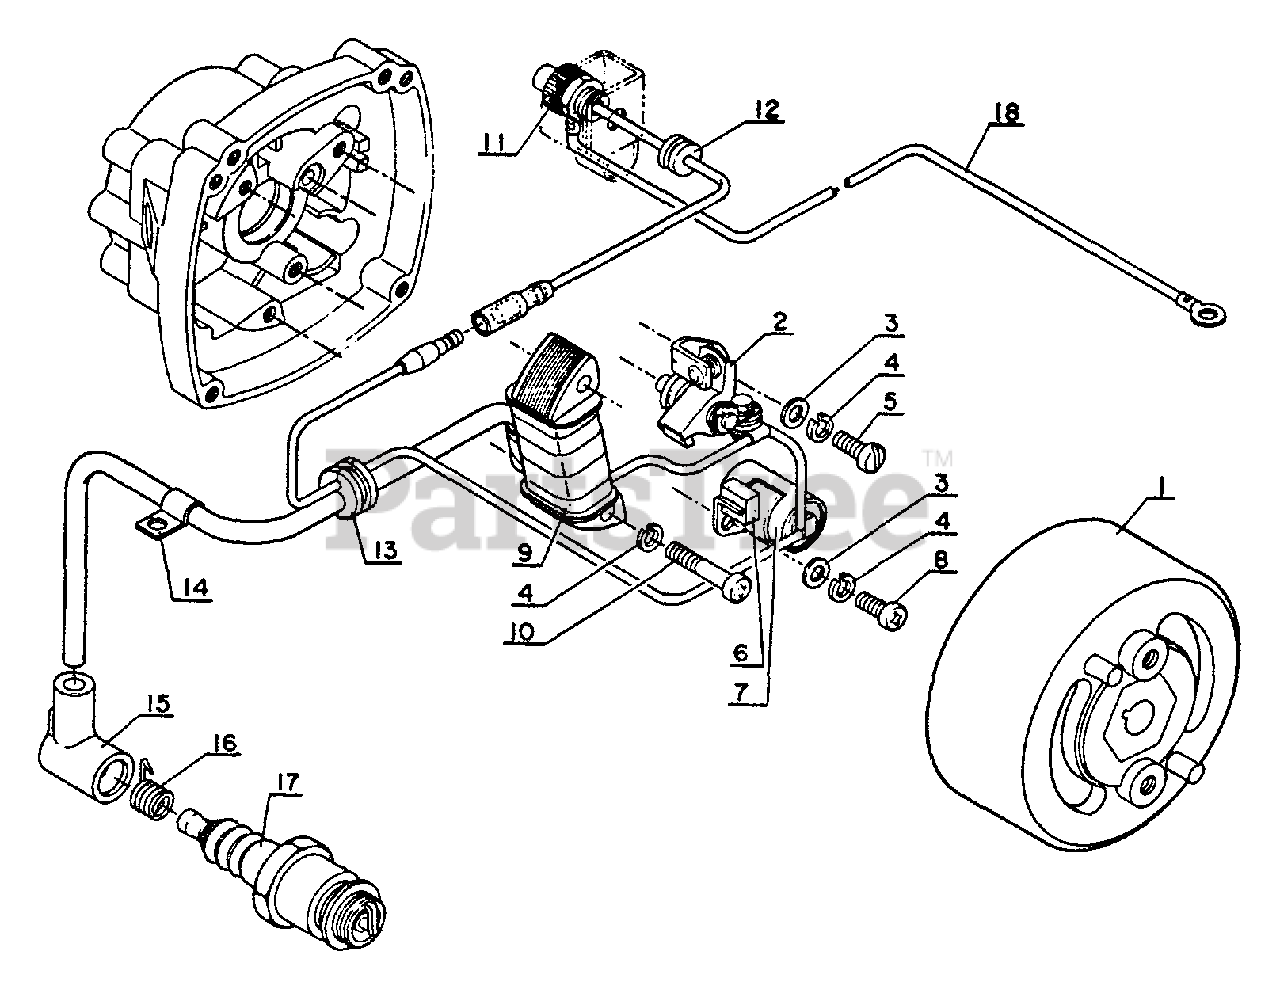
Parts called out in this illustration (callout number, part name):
1	FLYWHEEL
2	CONTACT POINT SET
3	WASHER 4 MM
4	WASHER, SPRING 4 MM
5	SCREW 4×8
6	PAD, OIL
7	CONDENSER
8	SCREW 4×8
9	COIL, IGNITION
10	SCREW 4×25
11	BUTTON, STOP
12	GROMMET
14	CLAMP
15	CAP, SPARK PLUG
16	TERMINAL, SPARK PLUG CAP
17	SPARK PLUG - BM6A
18	LEAD - GROUND
